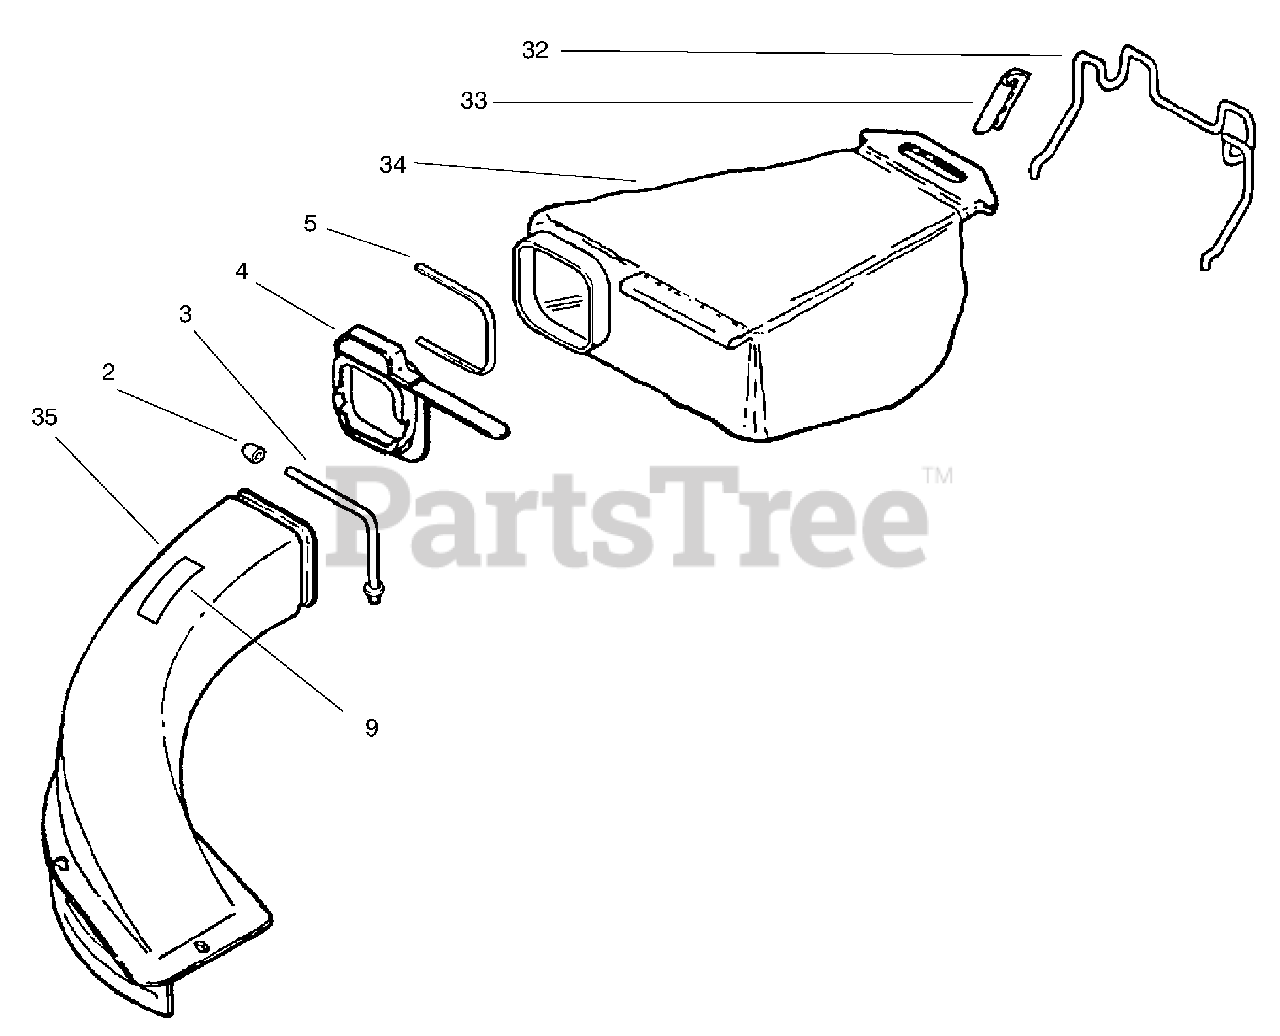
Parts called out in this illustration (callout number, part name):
2	Nut-Cap
3	Support-Chute
4	ASM-Adapter
5	Tie Strap
9	Decal-Danger
32	Wire Hanger,
33	Clamp-Hanger
34	Bag & Adapter ASM
35	Chute & Support
